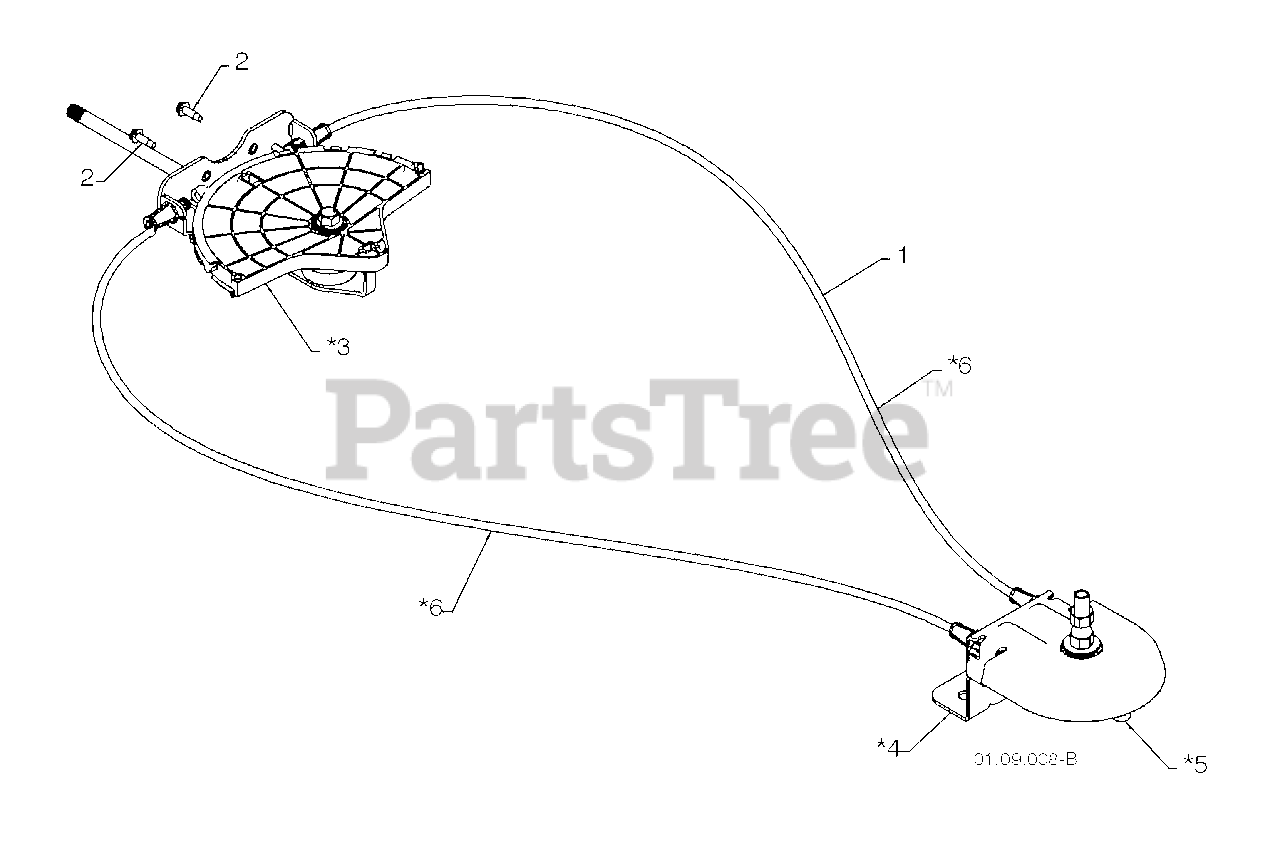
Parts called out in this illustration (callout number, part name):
1	LEVER/CABLE ROTATOR ASSEMBLY GRAY
2	SCREW 10-24 X .625
3	ROTATOR HEAD
4	ROTATOR PIVOT BRACKET
5	PULLEY PIVOT
6	CABLE ASSEMBLY GRAY
